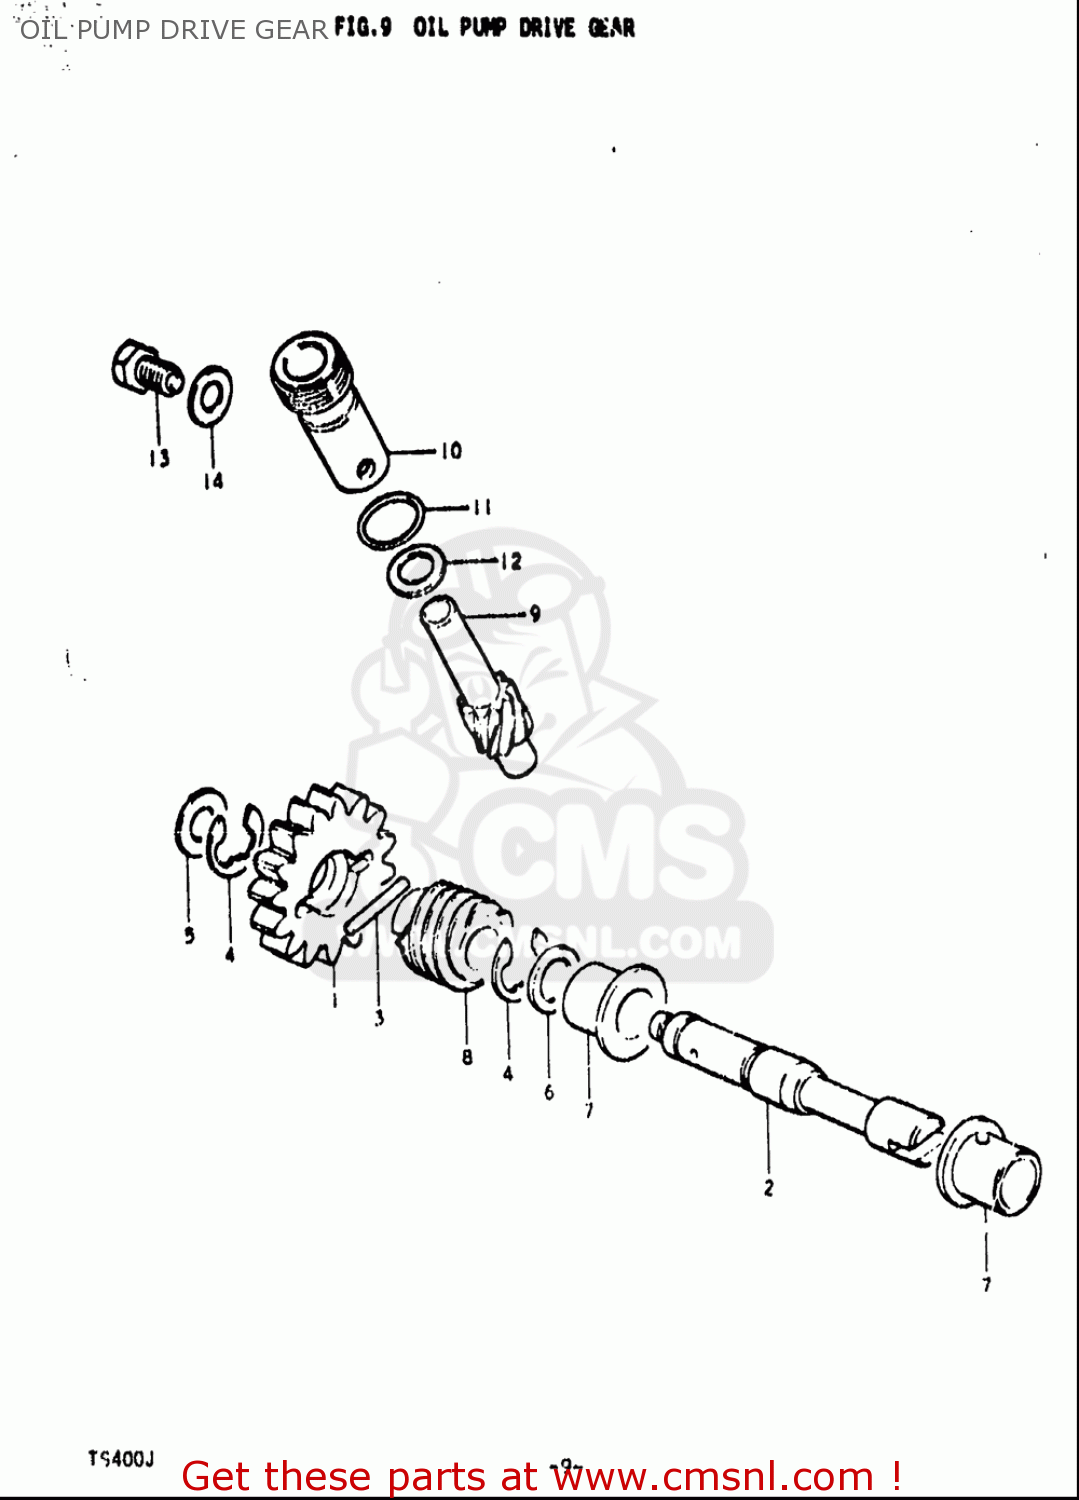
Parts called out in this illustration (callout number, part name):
3	ROLLER(4X23.8)
4	E RING
5	SHIM(8X16X1)
6	SHIM(10X16X1)
11	O RING(D:1.3,ID:9.6)
12	WASHER(8X13.7X1)
13	BOLT
14	WASHER
